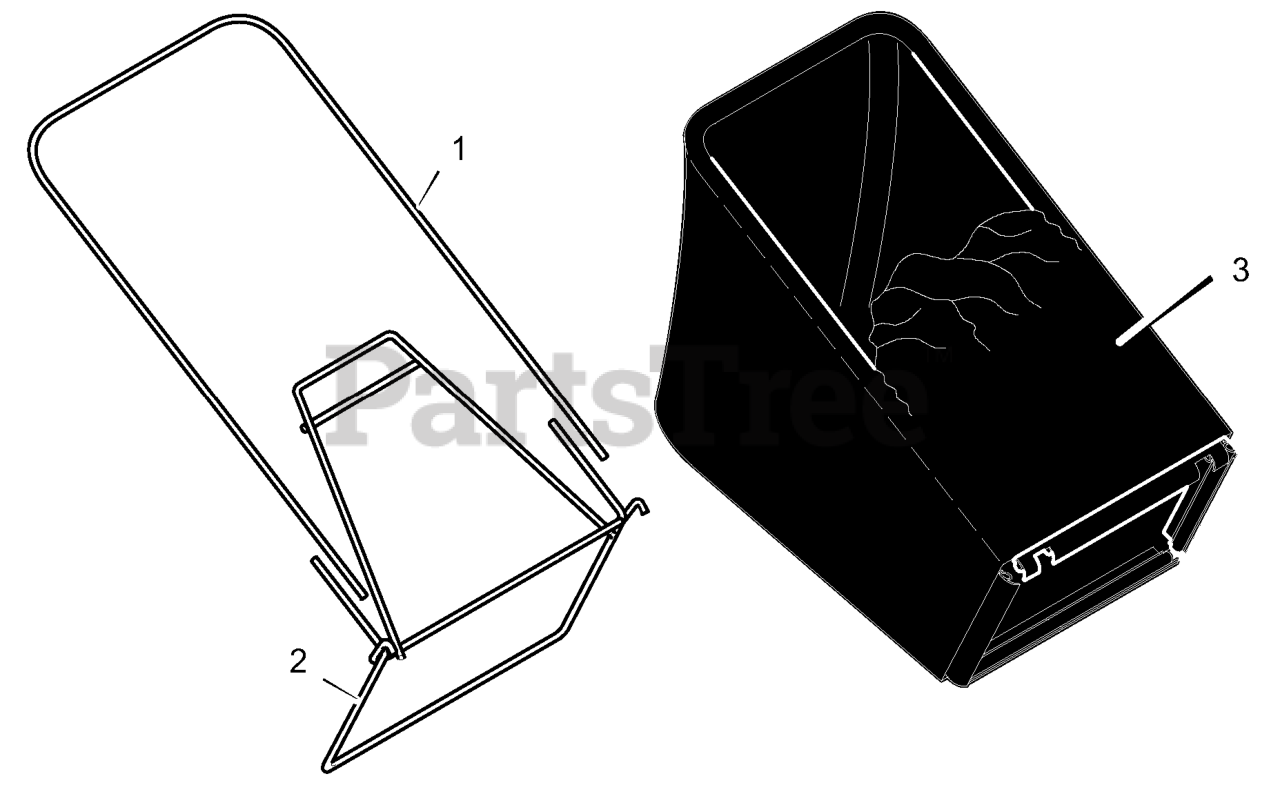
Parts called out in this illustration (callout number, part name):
1	Frame, Top
2	Frame Assembly
3	Bag, Cloth - Black
